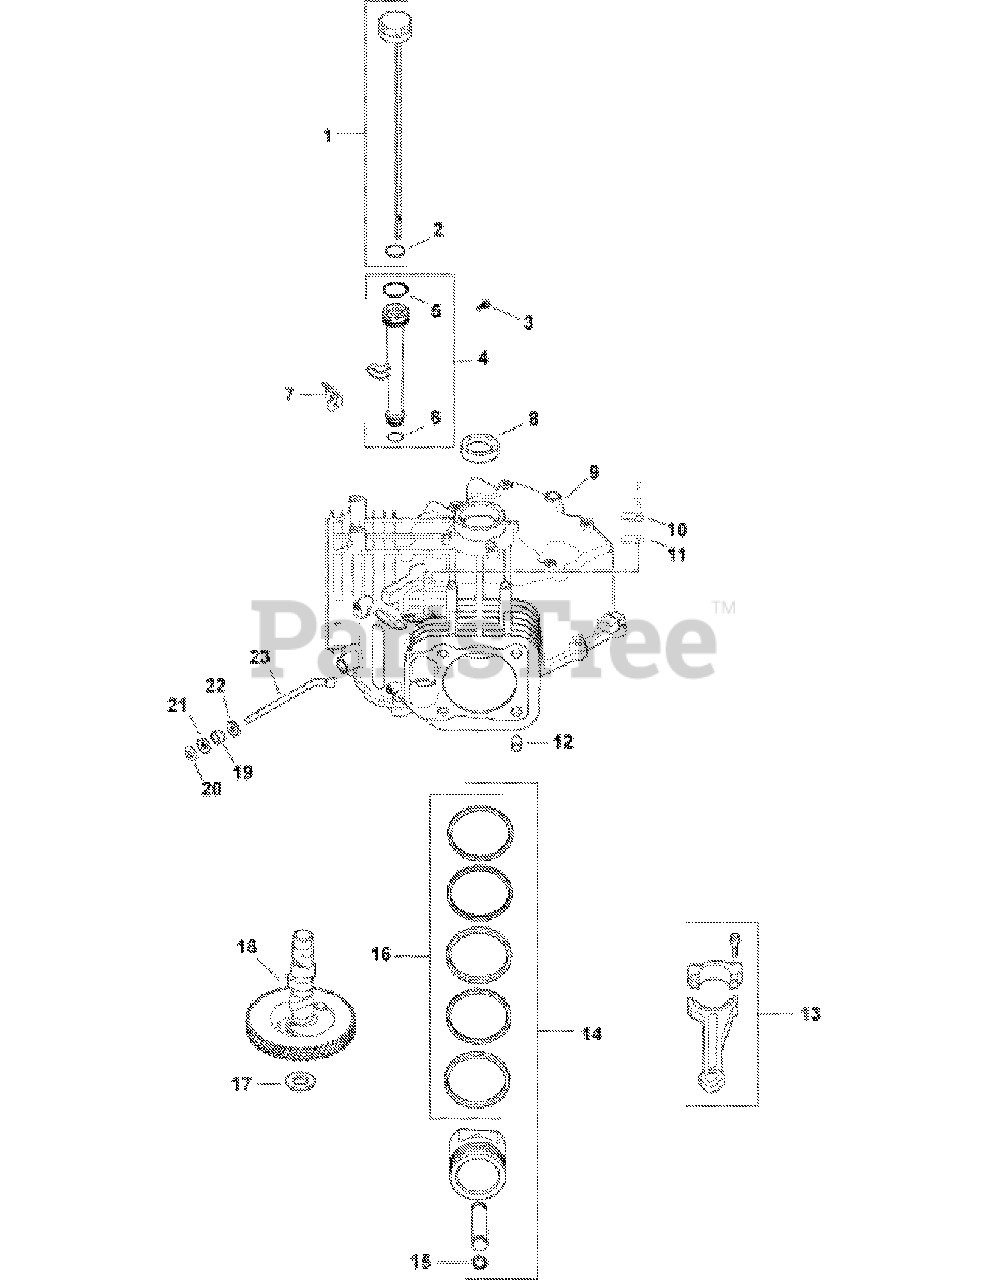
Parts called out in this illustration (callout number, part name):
1	DIPSTICK
2	O-RING, UPPER OIL FILL TUBE
3	SCREW, FLG THD FRM M5X0.8X13
4	KIT, OIL FILL TUBE - USE 12 123 35-S
5	O-RING, UPPER OIL FILL TUBE
6	O-RING, LOWER OIL FILL TUBE
7	BRACKET, OIL FILL TUBE
9	CRANKCASE
9	Short Block
10	RETAINER, BREATHER REED
13	CONNECTING ROD (STD)
14	KIT, PISTON W/ RING SET (Std)
14	KIT, PISTON W/RING SET (.08)
14	KIT, PISTON W/RING SET (.25)
15	RETAINER, PISTON PIN
17	SHIM, CAMSHAFT (WHITE .028")
17	SHIM, CAMSHAFT (BLUE .03")
17	SHIM, CAMSHAFT (RED .032")
17	SHIM, CAMSHAFT (YELLOW .034")
17	SHIM, CAMSHAFT (GREEN .036")
17	SHIM, CAMSHAFT (GRAY .038")
17	SHIM, CAMSHAFT (BLACK .04")
19	SEAL, GOVERNOR CROSS SHAFT
21	WASHER, FLAT 9 MM
22	WASHER, FLAT 11/32"
23	SHAFT, GOVERNOR CROSS
